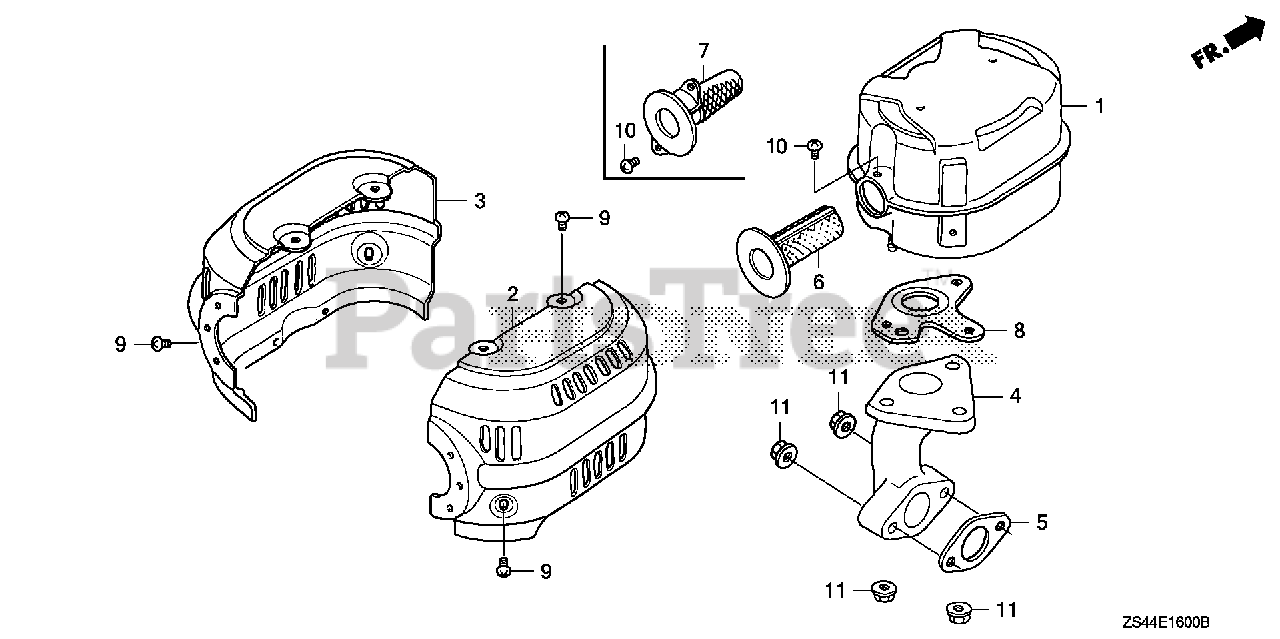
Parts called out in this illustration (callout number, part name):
1	MUFFLER (SILENT)
2	PROTECTOR, R. MUFFLER (SILENT)
3	PROTECTOR, L. MUFFLER (SILENT)
5	GASKET, EX. PIPE
6	ARRESTER, SPARK
8	GASKET, MUFFLER (ARRESTER) (NIPPON LEAKLESS)
9	SCREW, TAPPING (5X8)
10	SCREW, TAPPING (5X8)
11	NUT, FLANGE (8MM)
